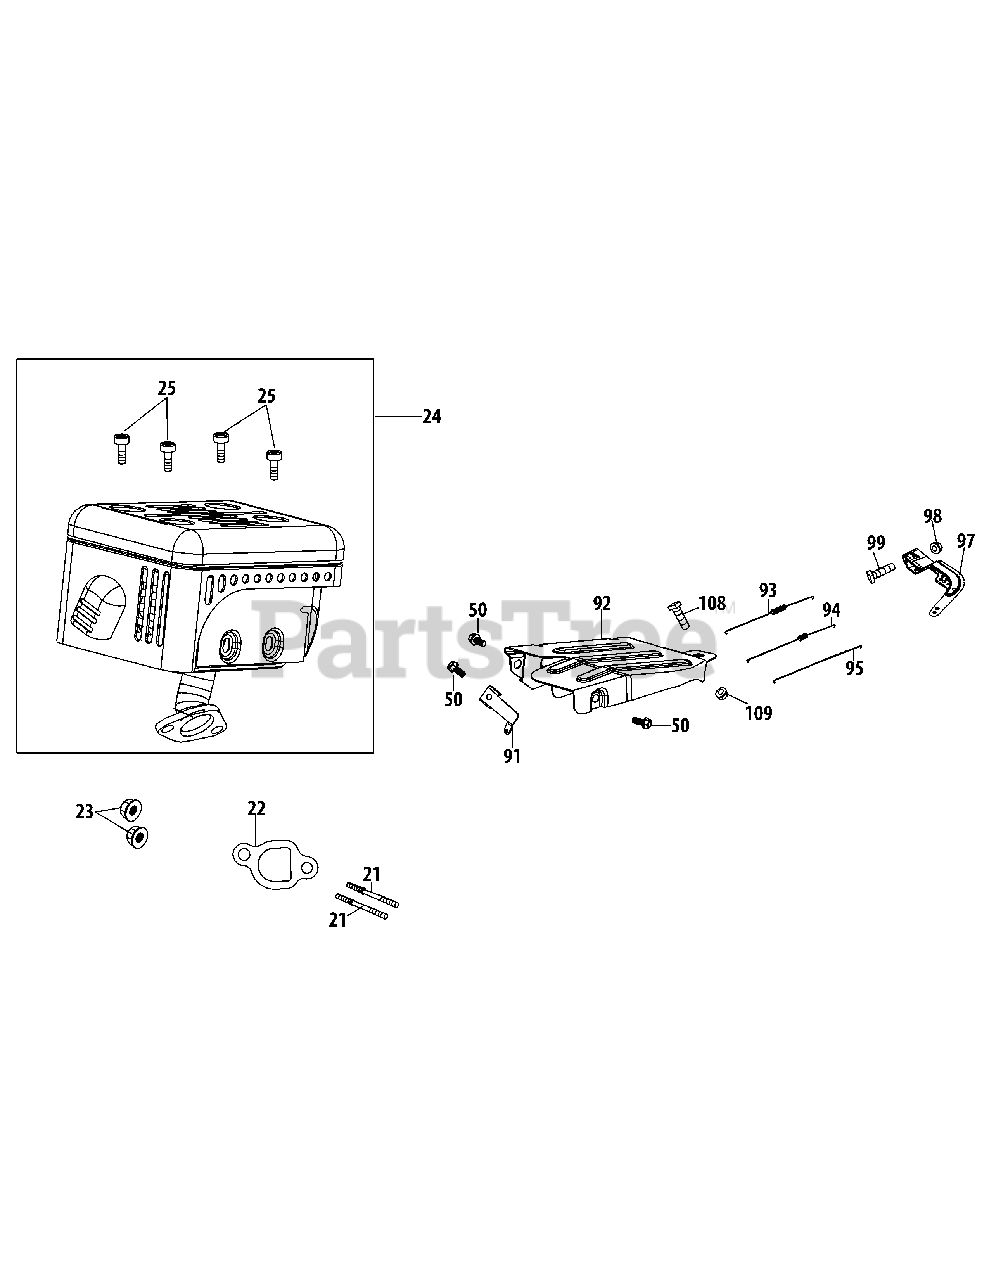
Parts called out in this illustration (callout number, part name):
21	Muffler Stud M8×36
21	Muffler Stud Assembly
22	Muffler Gasket
24	Muffler Assembly
25	Bolt M5×10
50	Bolt M6×12
91	Covernor Spring Bracket
92	Governor Shield
93	Governor Spring
94	Throttle Linkage Spring
95	Throttle Linkage
97	Governor Arm
98	Nut M6
99	Governor Arm Bolt
108	Bolt M6×28
109	Nut M6
